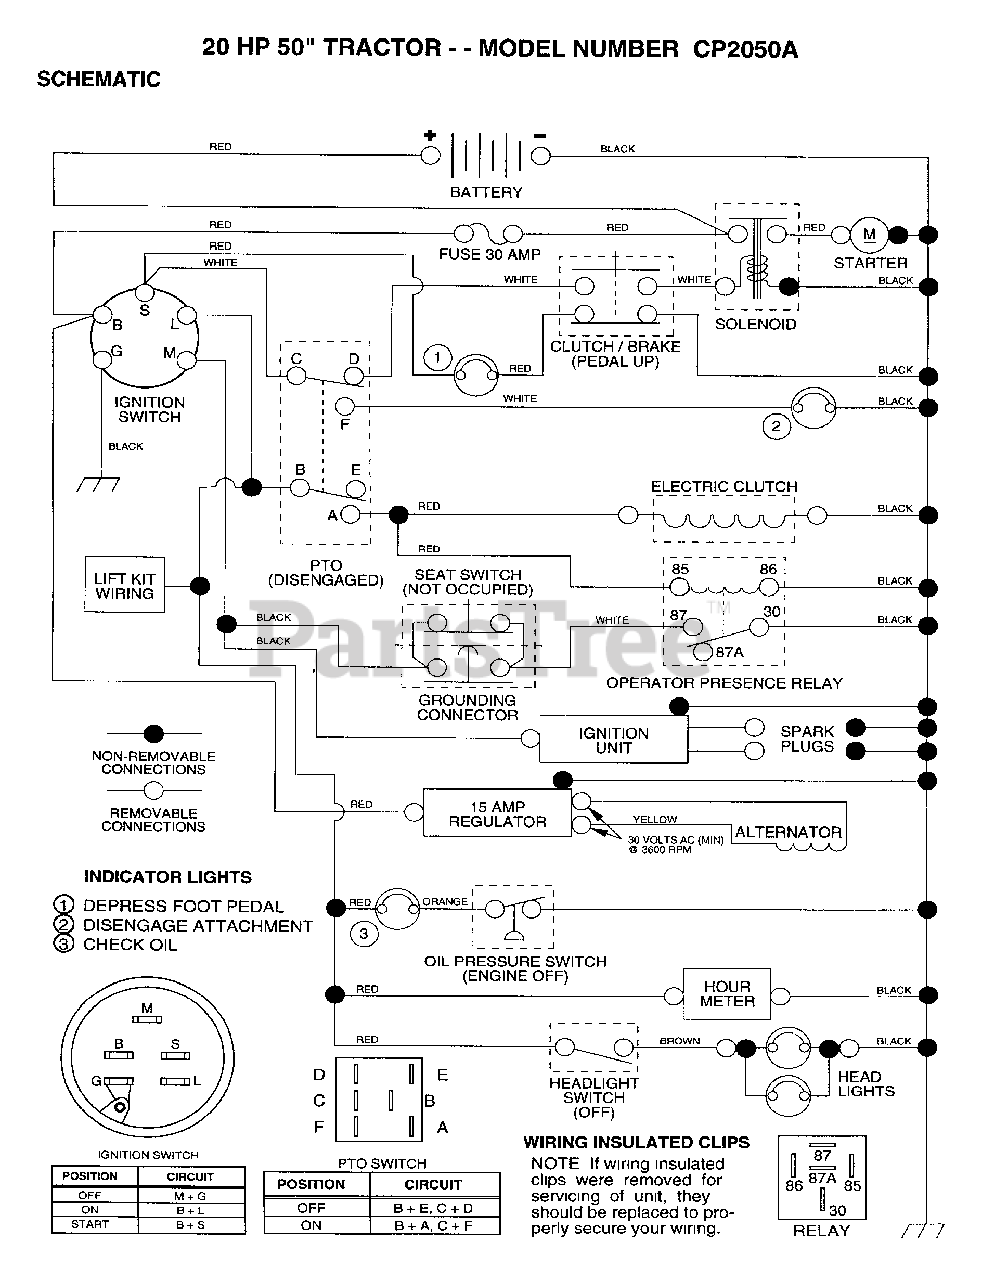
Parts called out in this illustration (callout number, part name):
1	DECAL.HOOD.LH
2	DECAL.HOOD.RH
3	DECAL.WHL.STRG.
5	DECAL
7	DECAL.CHASSIS 6SP
